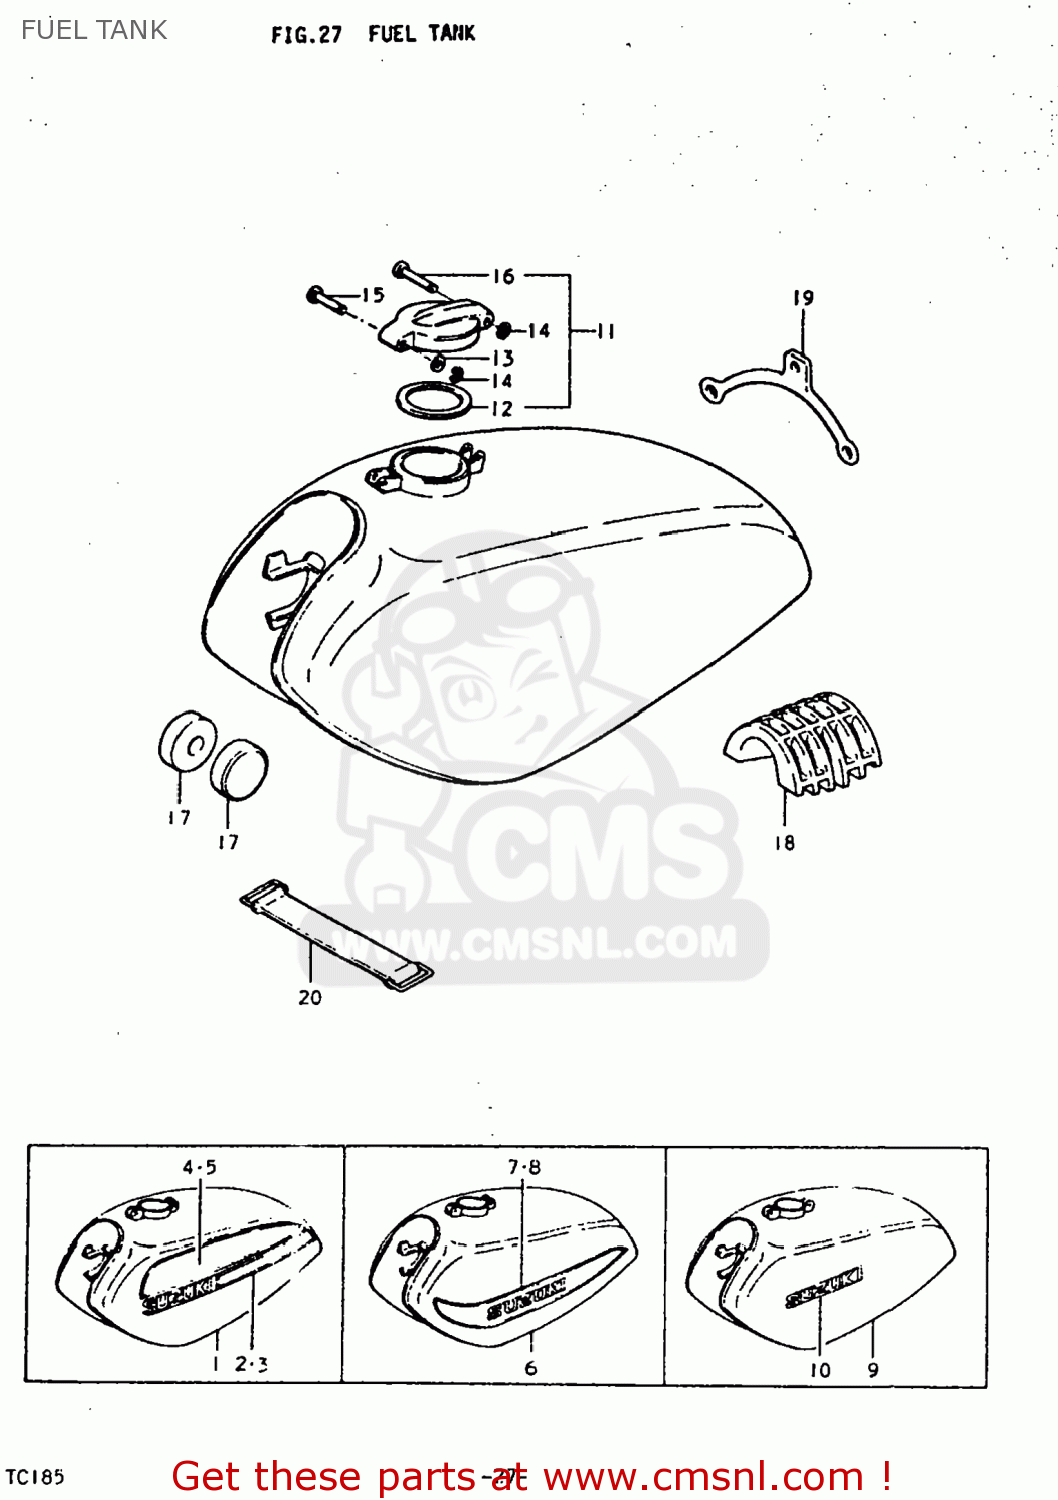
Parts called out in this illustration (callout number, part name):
1	TANK ASSEMBLY,FUEL
2	EMBLEM
3	EMBLEM,FUEL TANK
4	TAPE,FUEL TANK
5	TAPE,FUEL TANK
6	TANK ASSEMBLY,FUEL
7	TAPE,FUEL TANK
8	TAPE,FUEL TANK
9	TANK ASSEMBLY,FUEL
10	EMBLEM
11	CAP ASSEMBLY,FUEL TANK
12	GASKET (NAS)
13	WASHER
14	E RING
16	PIN,FUEL TANK C
17	CUSHION
18	CUSHION
19	BAND
20	BAND
